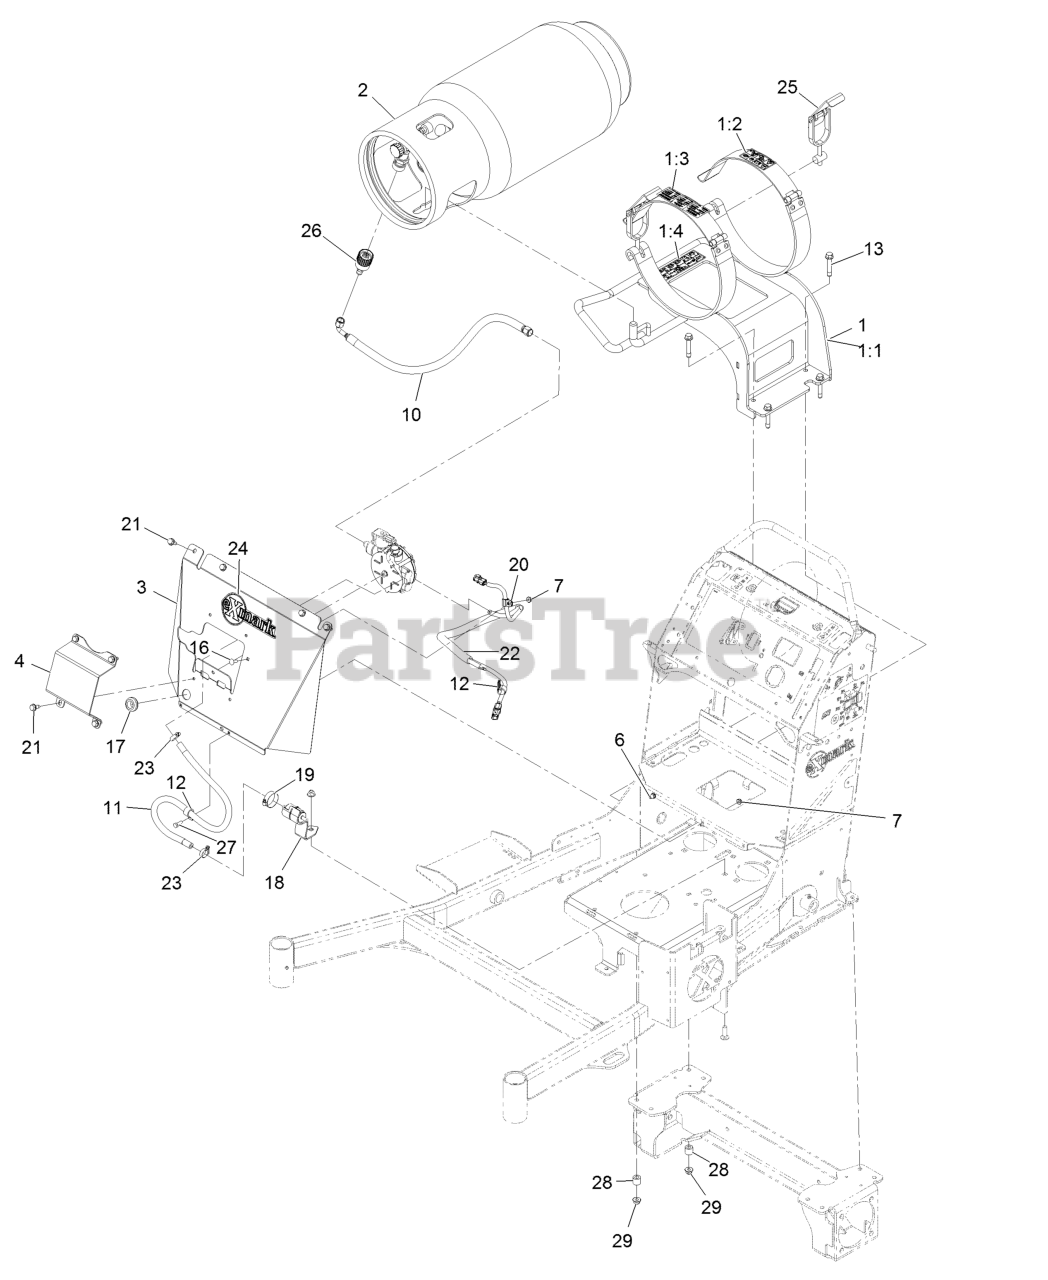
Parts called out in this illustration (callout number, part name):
1	ASM, LP Tank Mount W/Decal
1:1	Bracket-LPG Tank [black]
1:2	Decal-LPG Warning
1:3	Decal-LPG Horiz Tank Spec
1:4	Decal-LPG Fuel Tank Replacement
2	Tank, LP - 33.5 Lb.Horizontal-Al
3	Panel, Front
4	Guard, Regulator
6	Bolt-Carriage 1/4-20 X 3/4
7	Nut-Nyloc 1/4-20 Flg
10	ASM-Hose, LPG
11	Hose, Fuel
12	Clamp-Cable
13	Screw-HHF W/ Patch
16	Screw-CARR
17	Grommet
18	Bracket, Filter
19	Clamp-Hose
20	Clip-Loom
21	Screw-HWH 5/16-18 X 3/4 Tf
22	ASM, Vent Hose And Harness
23	Clamp-Hose
24	Decal, Exmark Logo
25	Latch, LP Tank
26	Connector-LP, Straight
27	Screw-HH 1/4-20 X 3/4
29	Nut-Nyloc 3/8-16 Flg
